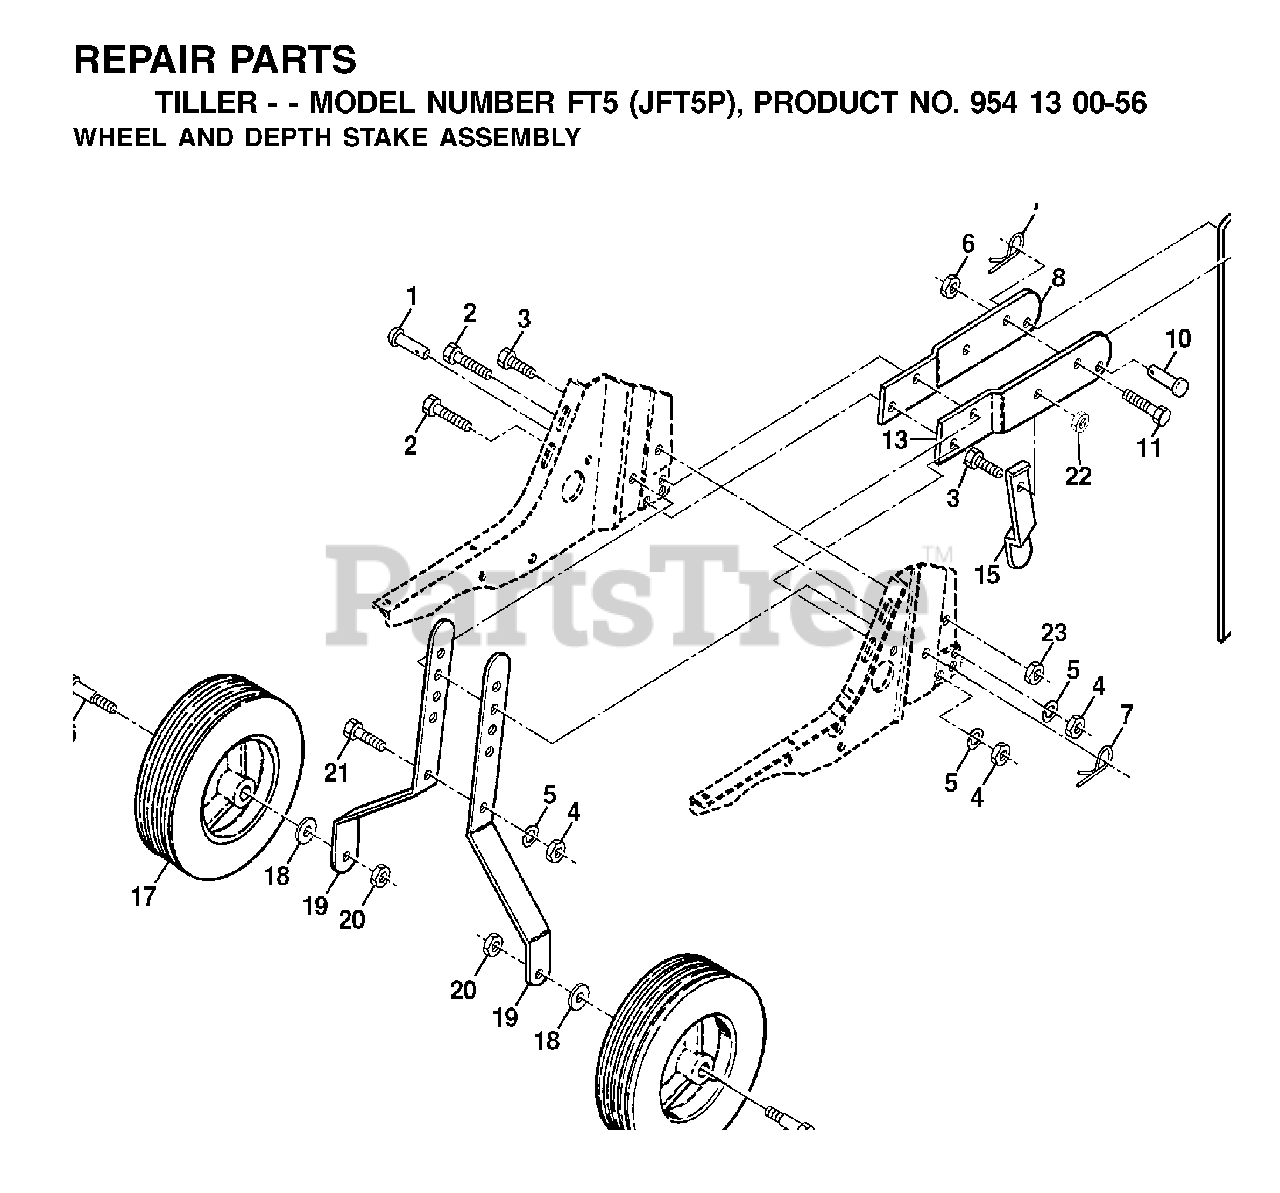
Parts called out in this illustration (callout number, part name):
1	PIN
2	BOLT
3	BOLT
5	LOCKWASHER
6	NUT
7	SPRING.RETAINER
8	SUPPORT.STAKE.RH.BLACK
9	RP STAKE.DEPTH.13.25.W/9HOLES
11	BOLT
16	BOLT.SHOULDER
18	WASHER
20	LOCKNUT
21	BOLT RB
22	NUT.71038.31-18.HEX.NYLOCK
23	LOCKNUT-FLANGE 5/16-18
